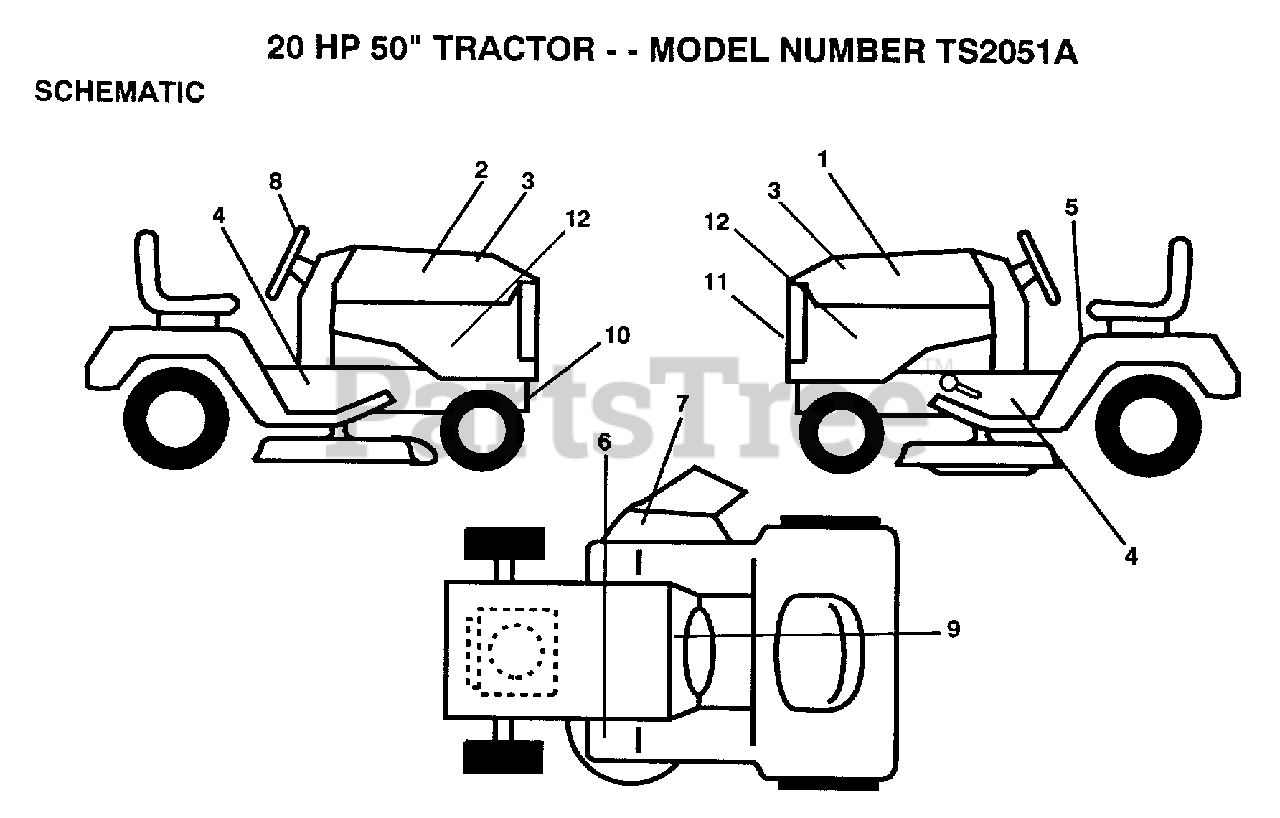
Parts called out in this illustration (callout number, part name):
5	DECAL
7	DECAL WARING
8	DECAL.STRG.WHL
11	PLATE.NAME.SMALL
12	DECAL.PANEL.SIDE
